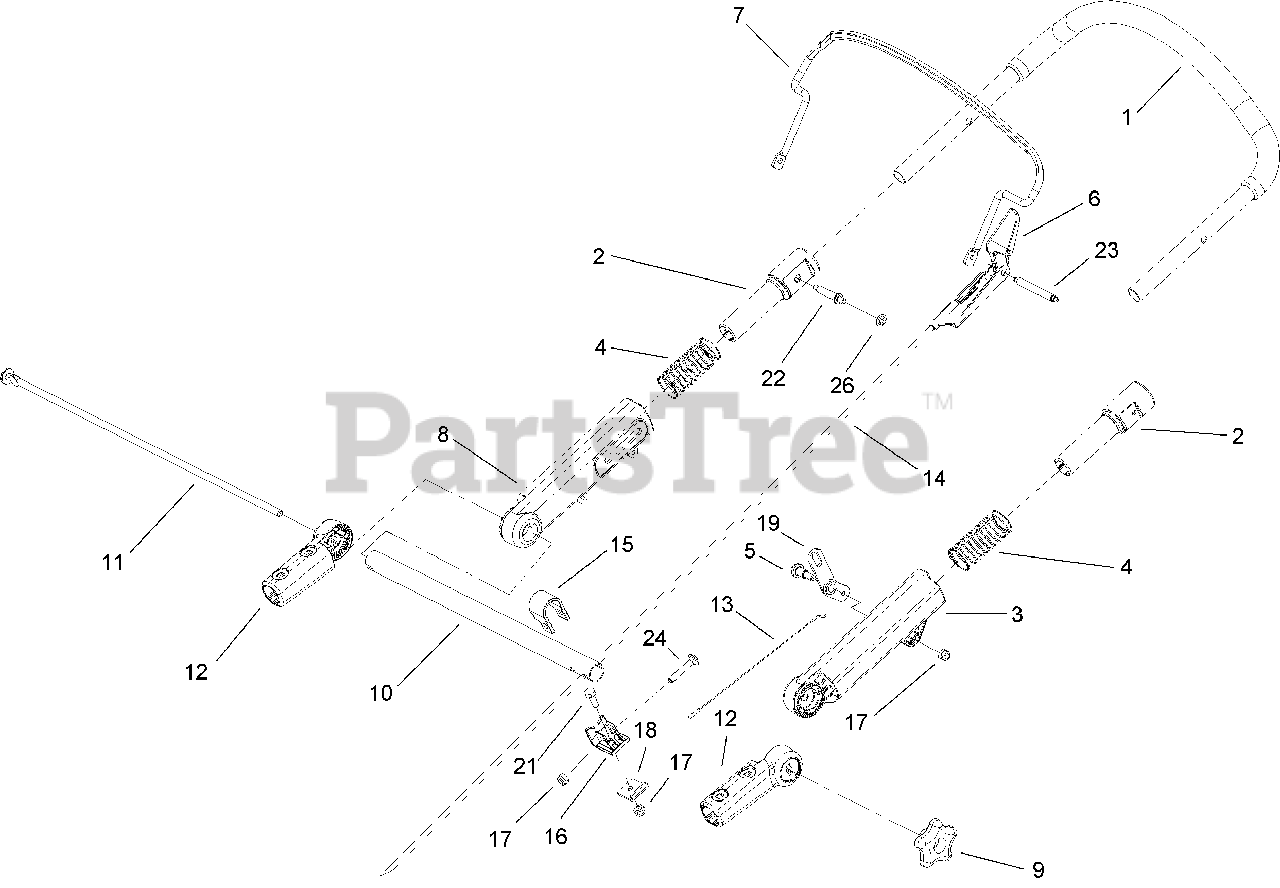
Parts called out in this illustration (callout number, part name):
1	UPPER HANDLE ASM
2	SLEEVE-HANDLE
3	SLIDE-TOP, LH
4	SPRING-COMPRESSION
5	BOLT-SHOULDER
6	STOP-BAIL
8	SLIDE-TOP, RH
11	ROD-THREADED
12	MOUNT-HANDLE, LOWER
13	CABLE-TRACTION
14	CABLE-BRAKE
15	SUPPORT-CABLE
16	SUPPORT-GUIDE, CABLE
17	NUT-LOCK, NI
18	CLAMP-CABLE
19	LEVER-TRACTION
21	SCREW-HH
22	PIN-HANDLE
23	PIN-BAIL, LH
24	SCREW-CARR
26	RETAINER-PUSH ON
